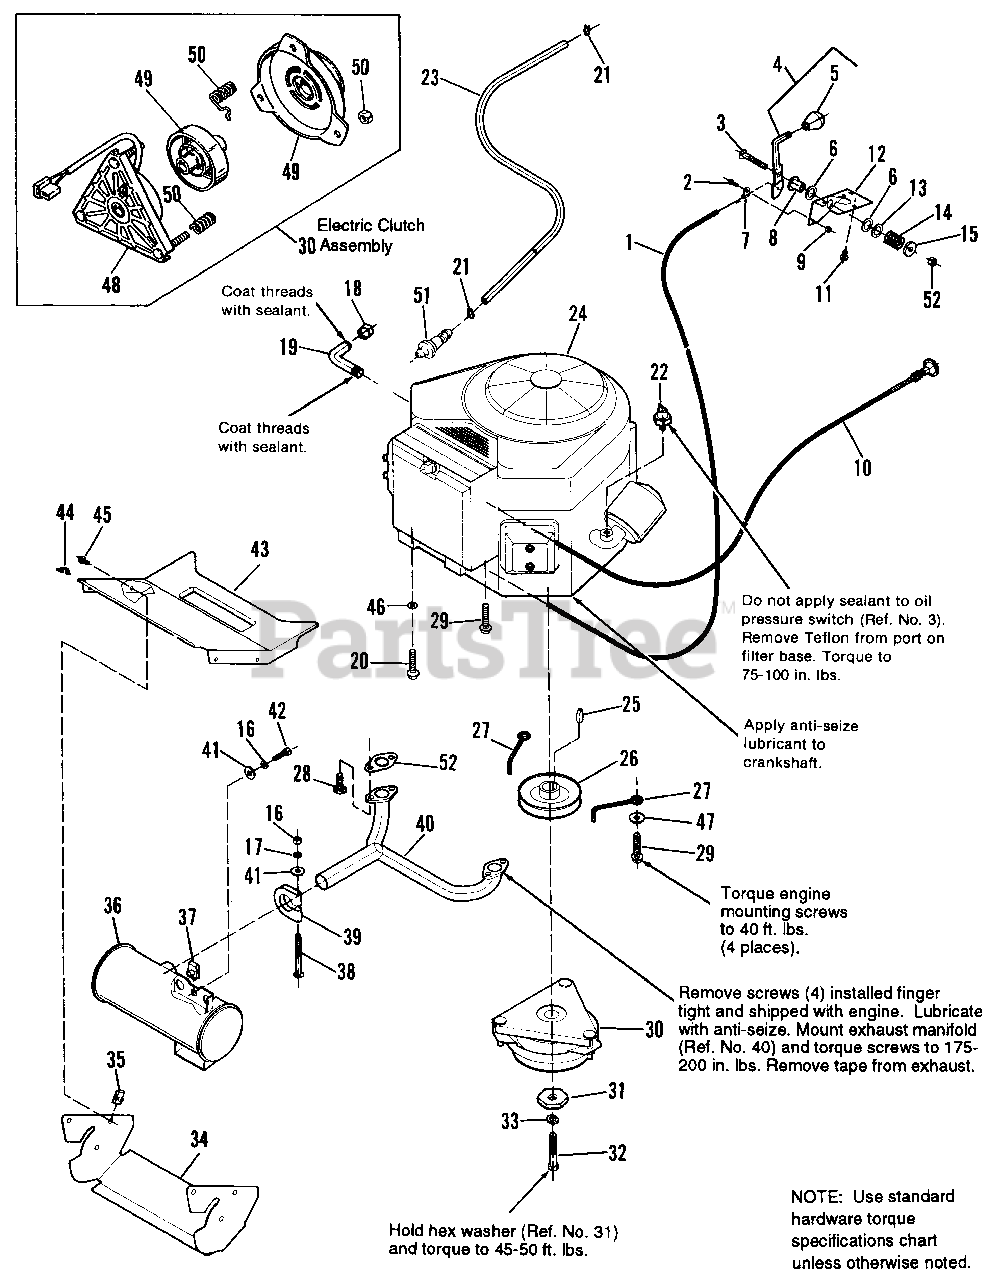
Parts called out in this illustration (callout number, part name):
1	CABLE, Throttle
2	SCREW, Trusshead, 10-32 x 1/2
3	CARRIAGE BOLT, 5/16-18 x 1-3/4
4	HANDLE, Throttle (Incl. Ref. No. 5)
5	KNOB, Throttle
6	WASHER, Nylon
7	CLIP, Bowden Wire
9	NUTASSY., 10-32
10	CABLE, Choke Control
11	SCREW, Plastite, 1/4-20 x 5/8
12	BRACKET, Throttle Mounting
15	WASHER, Plain, 5/16
16	LOCKWASHER, 5/16
17	NUT, Hex, Full, 5/16-18
20	SCREW, Taptite, 3/8-16 x 1-1/2
21	CLAMP, Hose
22	SWITCH, Oil Pressure
23	HOSE, Fuel, 45-1/2" Long
24	ENGINE, Twin Cylinder, 16 HP (Briggs & Stratton) ENGINE, Twin Cylinder, 12.5 HP (Briggs & Stratton)
25	KEY, Hi-Pro
26	PULLEY ASSY.
28	SCREW, Metric
29	SCREW, Taptite, 3/8-16 x 1-1/2
30	ELECTRIC CLUTCH (Incl. Ref. Nos. 48-50)
31	WASHER, Hex
32	CAPSCREW, 7/16-20 x 2-1/2
33	LOCKWASHER, 7/16
34	DUCT, Lower Muffler
35	PAL NUT, 1/4-20
36	MUFFLER ASSY.
37	PAL NUT, 5/16-18
38	CARRIAGE BOLT, 5/16-18 x 2-3/4
39	CLAMP, Muffler
40	MANIFOLD, Exhaust
41	WASHER, Plain, 11/32
42	CAPSCREW, Hex, 5/16-18 x 1
43	DUCT, Upper Muffler
44	CLIP
45	SCREW, Flange Whizlock, 1/4-20 x 5/8
46	LOCKWASHER, External Tooth
47	WASHER, Plain, 13/32
48	FIELD ASSY., Clutch
49	ROTOR & ARMATURE ASSY.
50	SPRING & NUT KIT
51	FUEL FILTER
52	NUT, Hex, Esna Lock, 5/16-18
